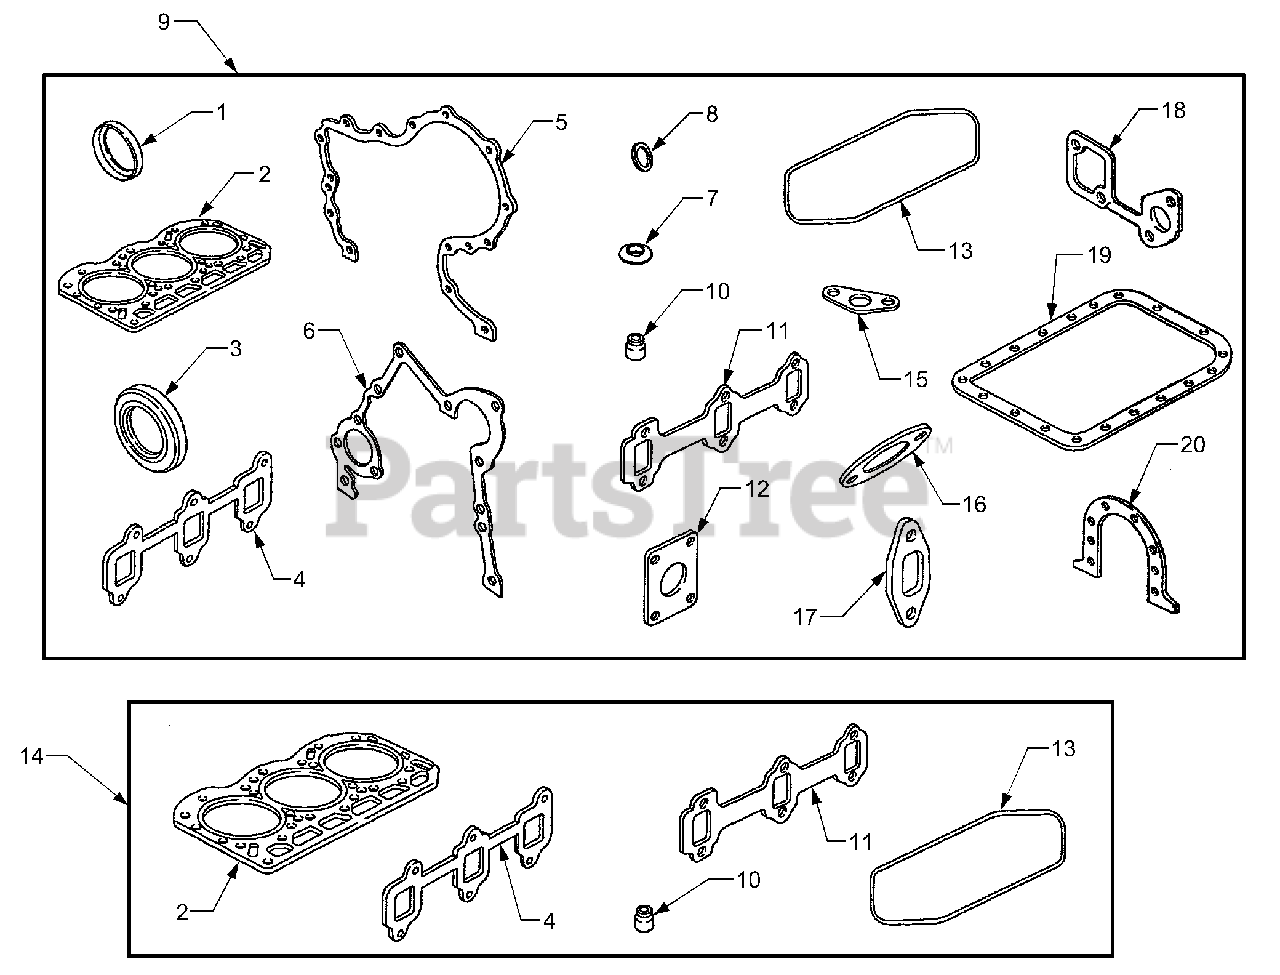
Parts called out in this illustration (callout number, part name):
1	Seal, Oil
2	Gasket, Cylinder Head
3	Seal, Oil
4	Gasket, Intake
5	Gasket, Gear Cover
6	Gasket, Gear Cover
7	Washer, Sealing
8	Washer, Sealing
9	Gasket Set
10	Seal, Valve
11	Gasket, Exhaust
12	Gasket, Exhaust
13	Gasket, Rocker Cover
14	Kit, Valve Overhaul
15	Gasket, Oil Pump Screen
16	Gasket, Outlet
17	Gasket, Inlet Housing
18	Gasket, Water Pump
19	Gasket, Oil Pan
20	Gasket, Retainer
